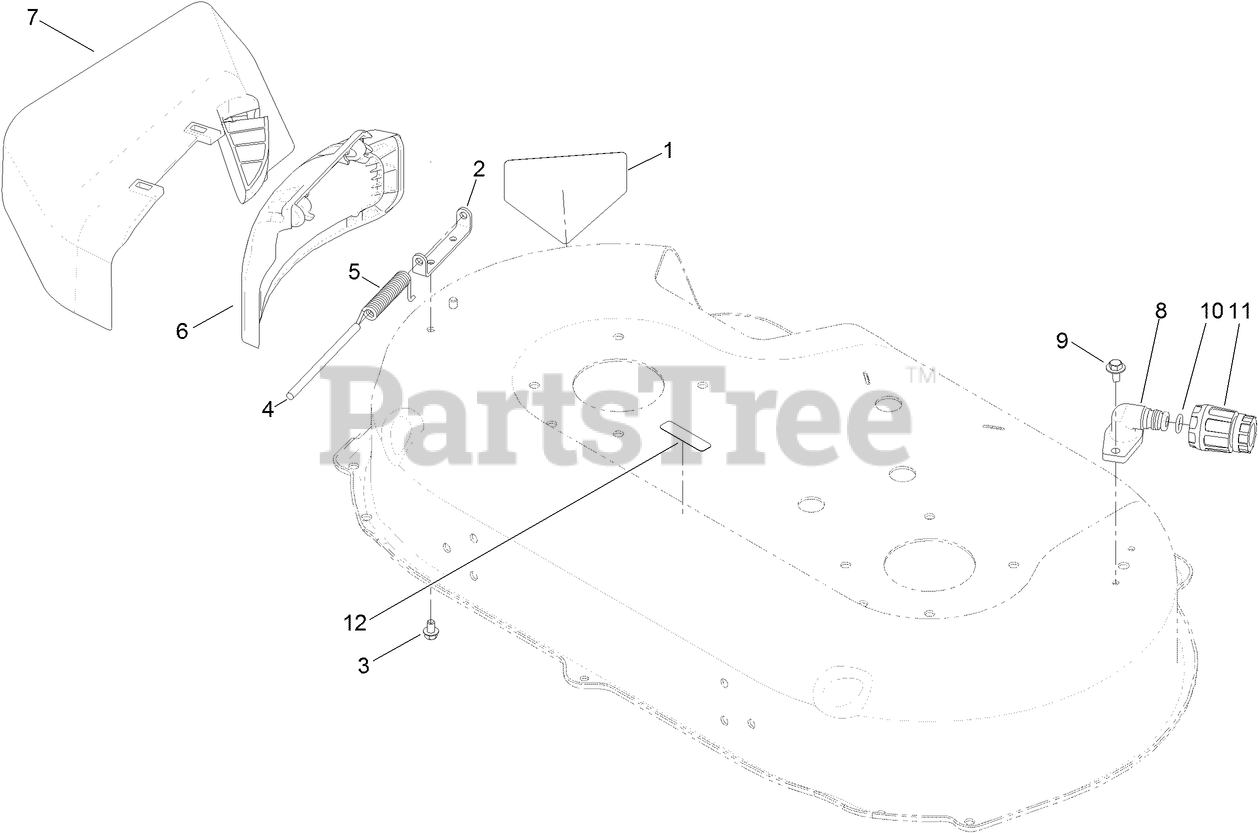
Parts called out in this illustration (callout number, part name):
1	DECAL-DANGER
2	BRACKET-COVER
3	SCREW-HWH
5	SPRING-TORSION, COVER
6	DEFLECTOR-SIDE
7	SIDE DISCHARGE CHUTE ASM
9	SCREW-HHFTF
10	O-RING
11	CONNECTOR-HOSE
12	DECAL-WARNING
